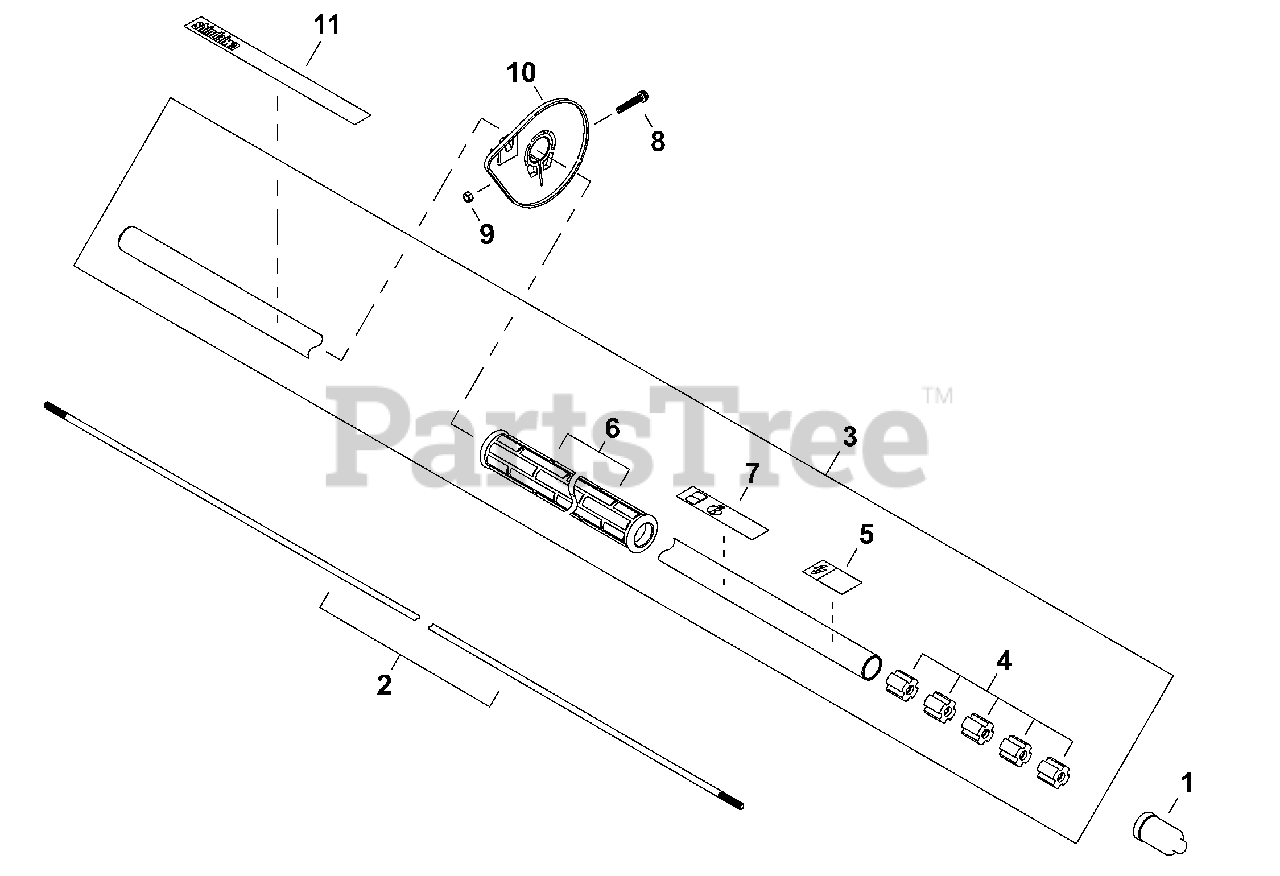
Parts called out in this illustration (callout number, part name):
2	MAINSHAFT
3	MAIN PIPE ASSY WITH GRIP
4	BUSHING
5	LABEL, HIGH VOLTAGE
6	GRIP, FRONT
7	LABEL, CAUTION
8	SCREW M5×30
9	NUT M5
10	GUARD, HAND
11	LABEL, SHINDAIWA PROFESSIONAL
